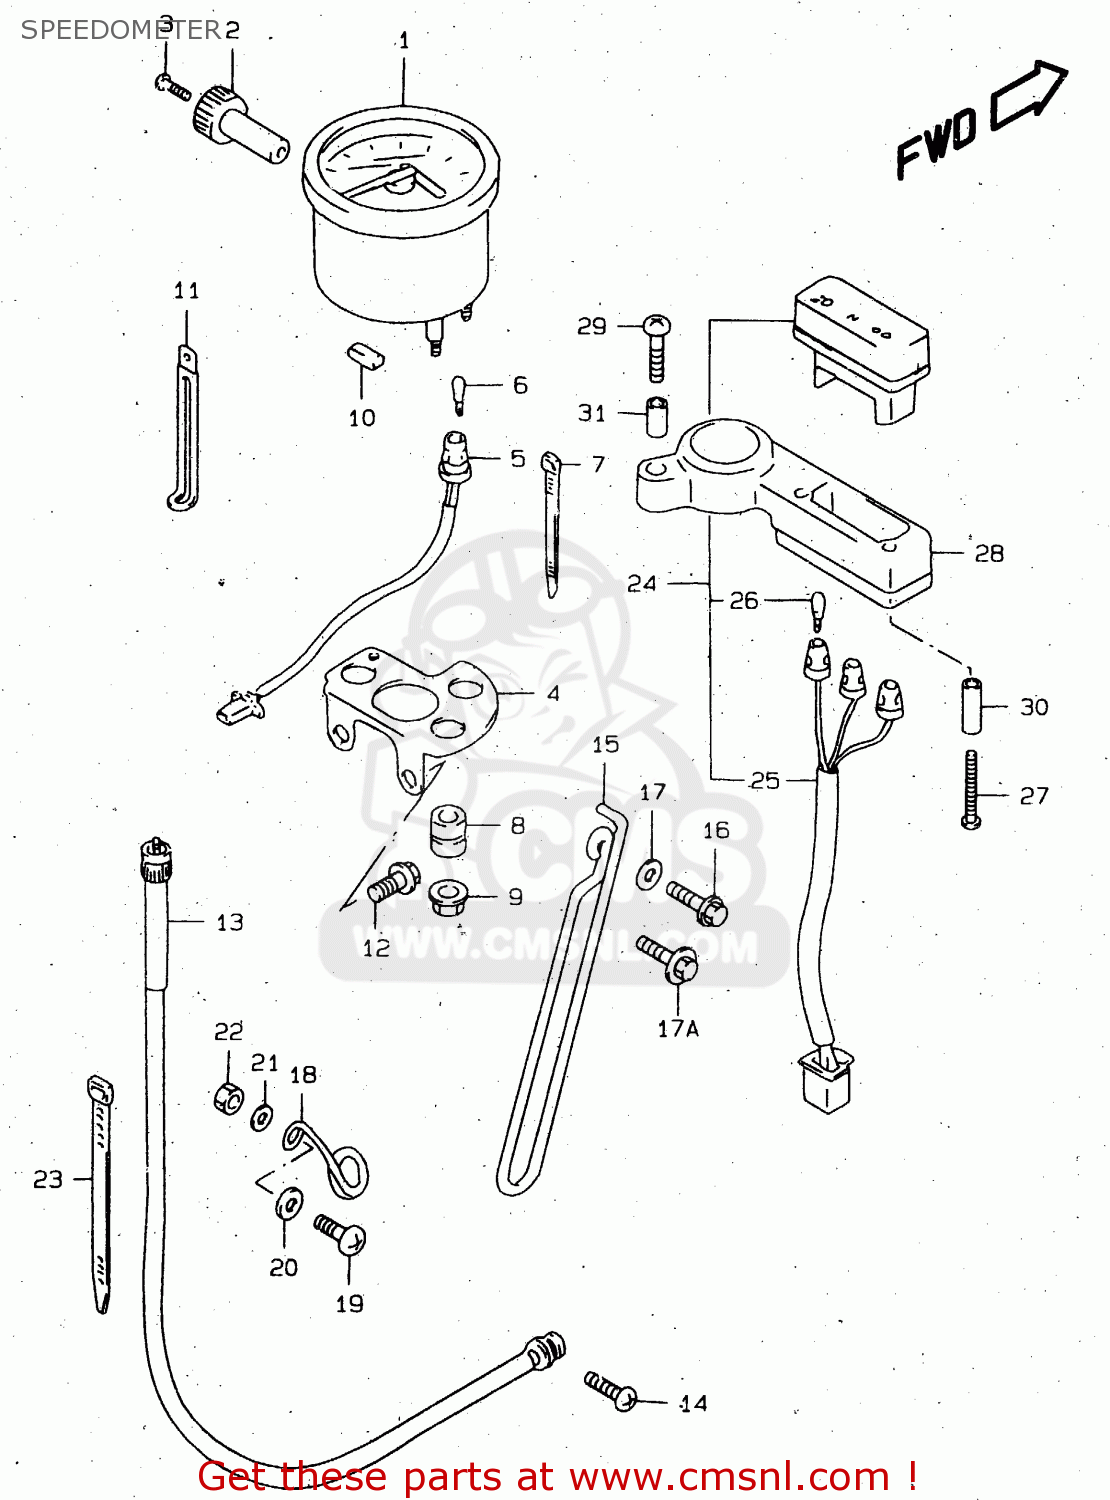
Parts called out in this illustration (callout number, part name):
1	SPEEDOMETER
2	KNOB,TRIP
3	SCREW,TRIP KNOB
4	BRACKET,METER
5	SOCKET,METER
6	BULB(12V3W,WB371,T7)
7	CLAMP
8	CUSHION
9	NUT
10	CUSHION
11	CLAMP(L:97)
12	BOLT
13	CABLE ASSY,SPEEDOMETER
14	SCREW
15	GUIDE,METER CABLE NO.2
16	SCREW
17	WASHER(6.5X20X1.6)
17A	BOLT(6X20)
18	GUIDE,SPEEDOMETER CABLE
19	SCREW
20	WASHER
21	WASHER
22	NUT 6MM
23	CLAMP(L:125)
24	BOX ASSY,PILOT LAMP
25	SOCKET & CORD
26	BULB(13.5V,2W,A7427)
27	SCREW
28	HOLDER,PILOT BOX
29	SCREW(6X25)
30	SPACER(4.5X6.5X25)
31	SPACER(6.1X8X15.5)
